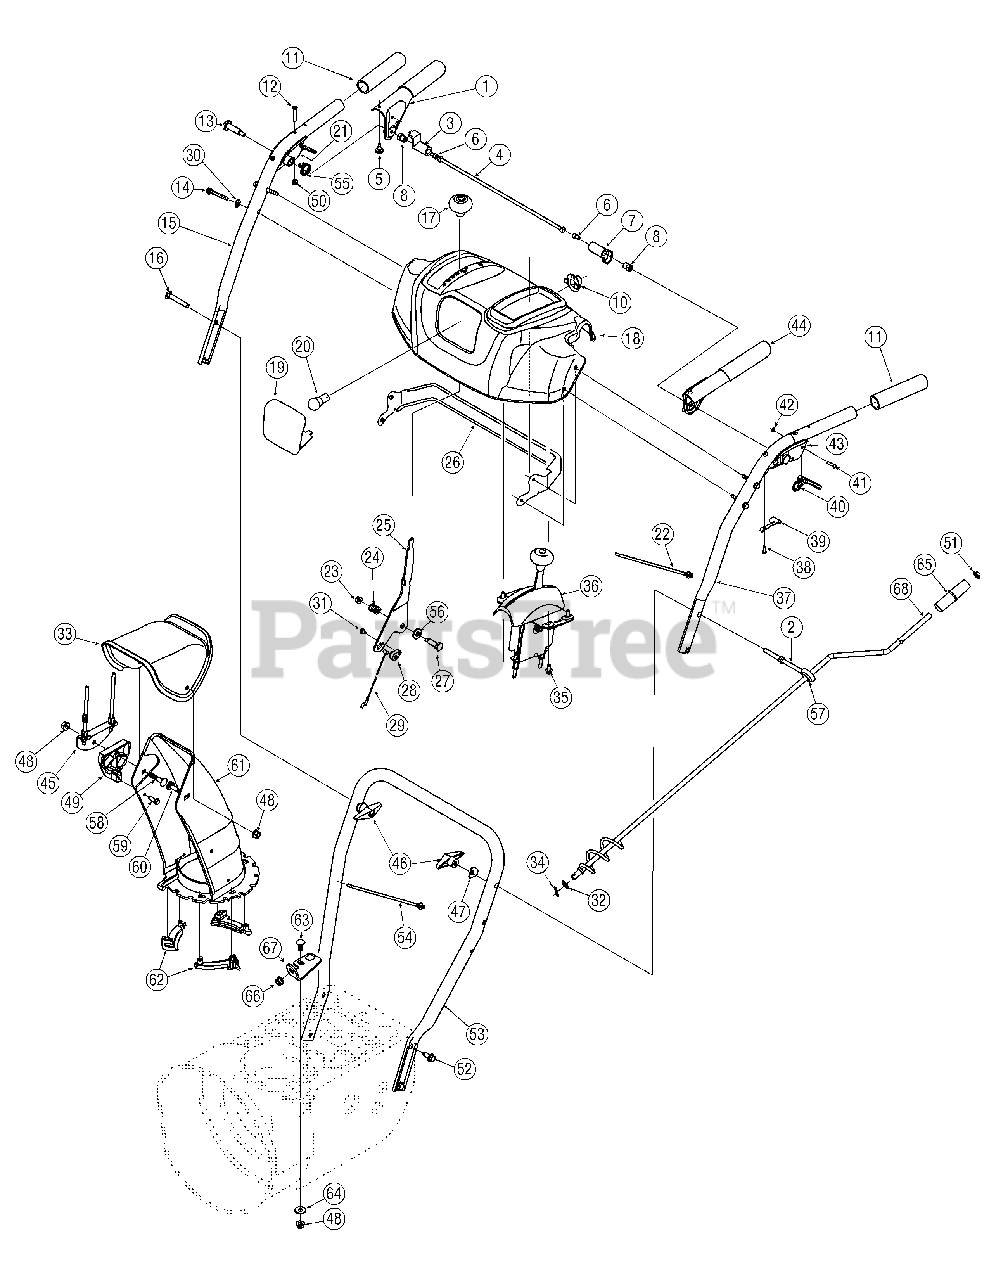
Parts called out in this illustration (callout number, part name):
1	Handle Engagement Assembly RH
3	Lock Plate
4	Pivot Rod
5	Rubber Bumper
6	Screw, 1/4-20 x.375
7	Clutch Lock Cam
8	Shoulder Nut, 1/4-20
10	Light Socket
11	Handle Grip
12	Screw, #10-24 x 0.375
13	Shoulder Screw, 1/4-20 x 1.345
14	Screw, 1/4-20 x 1.750
16	Carriage Screw, 5/16-18 x 2.25
17	Shift Knob
18	Handle Panel (Includes Ref. #19)
20	Lamp
21	Handle Clutch Lock - RH
22	Cable Tie
23	Flange Lock Nut, 1/4-20
24	Compression Spring
28	Cable Barrel Holder
29	Speed Selector Cable
30	Flat Washer, .25 x .630 x .0515
31	Screw, #10-16 x .500
32	Flat Washer, .375 x .738 x .063
33	Upper Chute
34	Cotter Pin
35	Hi-Lo Screw, 1/4-15 x 0.5
36	2-Way Chute Control™ Assembly
38	Screw, #8-16 x 0.50
39	Clutch Lock Spring
40	Steering Control
43	Handle Clutch Lock - LH
44	Handle Engagement Assembly LH
46	Handle Knob Assembly
47	Saddle Washer
48	Flange Lock Nut, 5/16-18
49	Chute Tilt Cable Guide
50	Hex Lock Nut, #10-24
52	AB Screw, 5/16-12 x 0.75
54	Cable Tie
55	Torsion Spring
56	Flat Washer
57	Rubber Grommet
58	Carriage Bolt, 5/16-18 x 1.50
59	Hi-Lo Screw, 1/4-15 x .75
60	Carriage Bolt, 5/16-18 x 1.0
61	Lower Chute Ass’y (Incl. Ref #62)
61	Lower Chute Only
62	Flange Keeper
63	Carriage Screw, 5/16-18 x 1.00
64	Flat Washer, .349 x .879 x .063
65	Chute Directional Control Knob
66	Plastic Bushing
